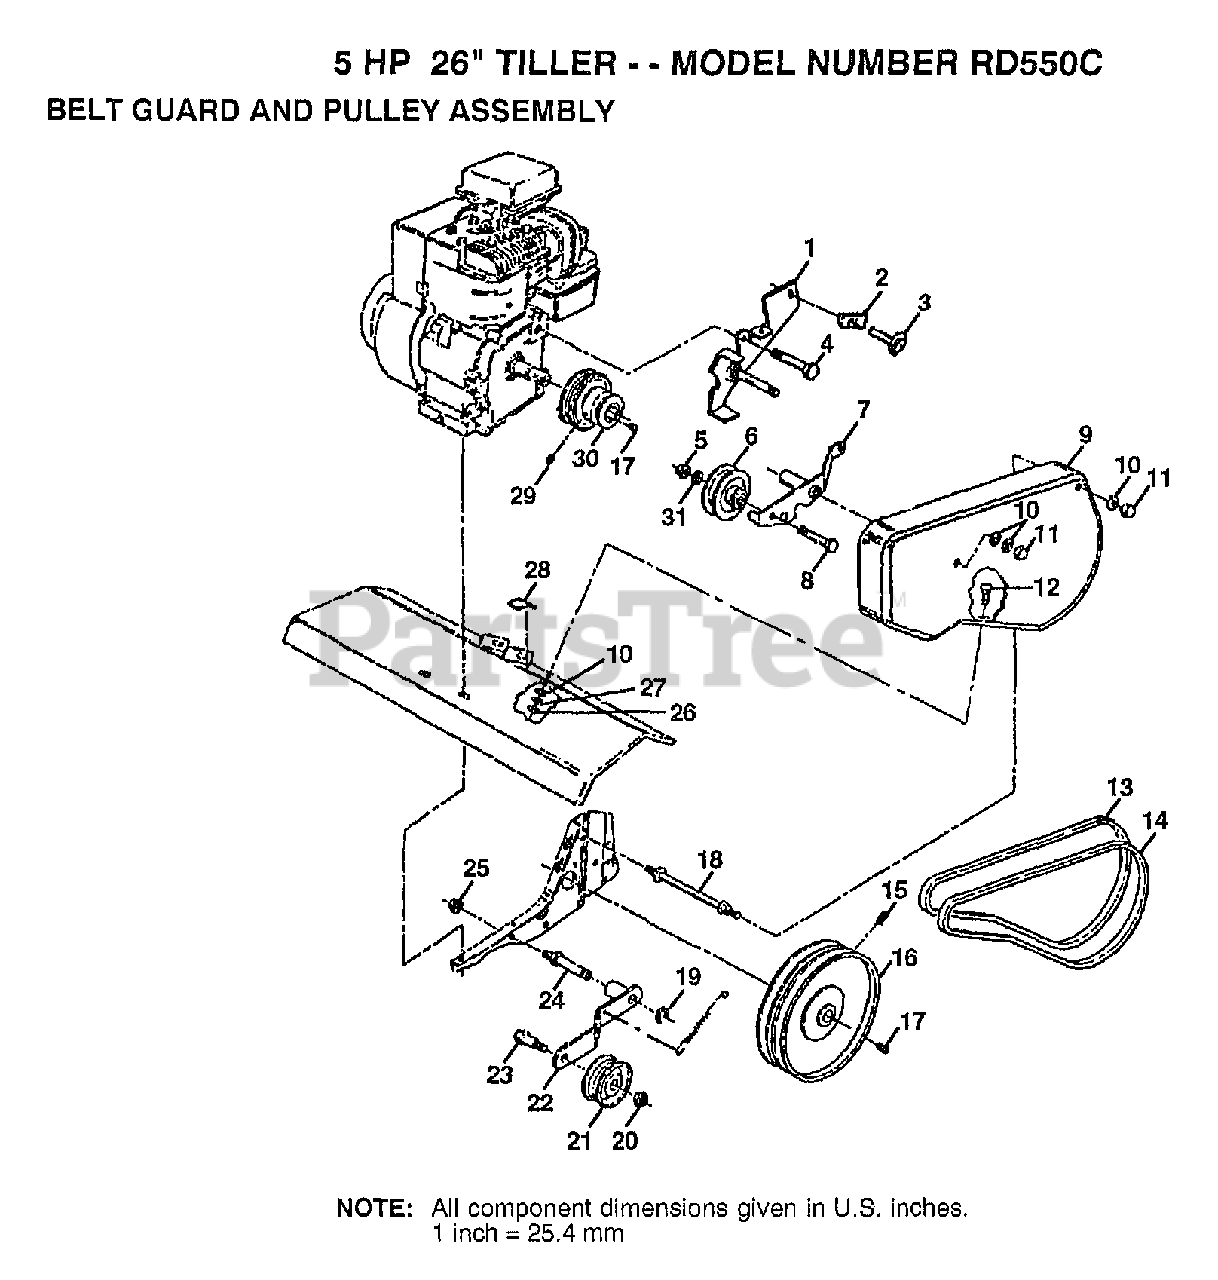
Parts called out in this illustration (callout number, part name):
2	CONDIUT CLIP T
5	NUT.HEX.3/8-16UNC
6	PULLEY W/SPACER
7	ARM.ASM.REV.IDLER
10	WASHER
11	NUT-CAP TI
12	BOLT T
13	BELT-V
15	SET SCREW
17	KEY T
18	BOLT TI
19	KLIP RING TI
20	NUT
22	IDLER ARM TI
24	SHAFT IDLER TI
25	JAM NUT TI
27	LOCKWASHER
28	PAD IDLER TI
29	SET SCREW
30	ENGINE PULLEY TI
31	WASHER
